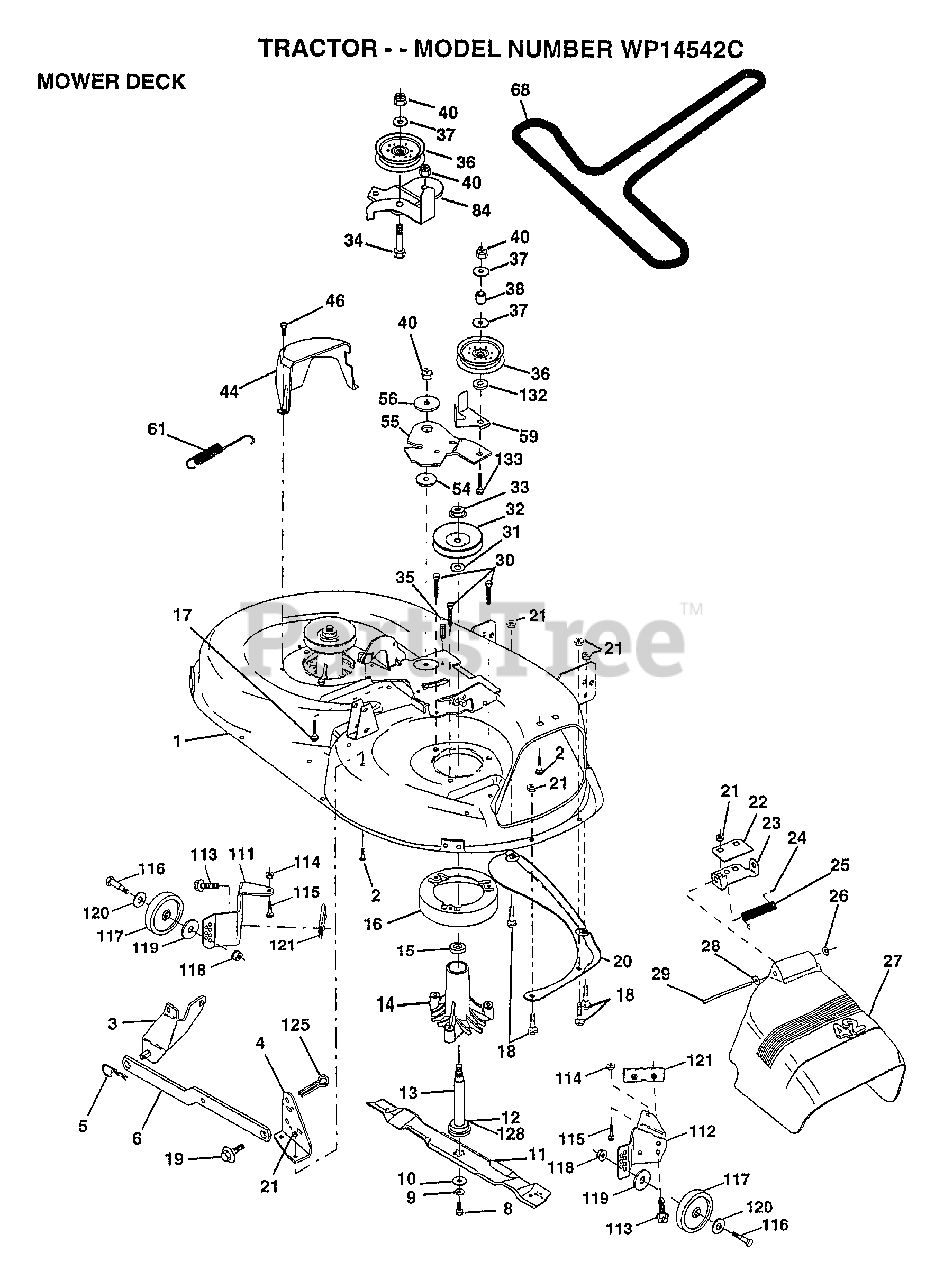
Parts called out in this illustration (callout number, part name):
1	DECK.WELD.42.
2	BOLT
3	BRKT ASM SWAY BAR
4	BRKT DECK SW BAR
8	BLADE BOLT
10	WASHER.HARD.BLADE
11	"BLADE.42"" HIPERF"
12	BEARING.BALL
14	HSG ASM MANDREL
15	BEARING
16	STRIPPER RND MWR
17	BOLT CARRIAGE
18	BOLT
19	BOLT SHD 5/16-18
22	STIFFENER BRKT
23	DEFLECTOR BRKT
24	CAP-SLEEVE LT
25	SPRING TORSION
26	NUT PUSH M
27	DEFLECTOR.SHIELD
28	WASHER
29	HINGE ROD
31	WASHER
32	PULLEY.MANDREL.42
34	BOLT
35	XMAS TREE FASTNER
36	FLAT IDLER PULLEY
37	WASHER
44	GUARD MAND LH BLK
46	SCREW.1/4-20X5/8
54	HARDENED WASHER
56	SPACER RETAINER
59	GUARD IDLER TUV
61	SPRING.EXTENSION
68	BELT-V.SEC.46.KEL
84	BRACKET ASM IDLER
111	BRACKET.GWHL.LH.
112	BRACKET.GWHL.RH.
113	SCREW
116	BOLT M
117	WHEEL.GAGE.BLK.PL
118	LOCKNUT
119	WASHER
120	WASHER
121	BRACKET.EXTRD.GWL
125	COTTER PIN
128	WASHER.FELT.
132	WASHER GT
133	BOLT
